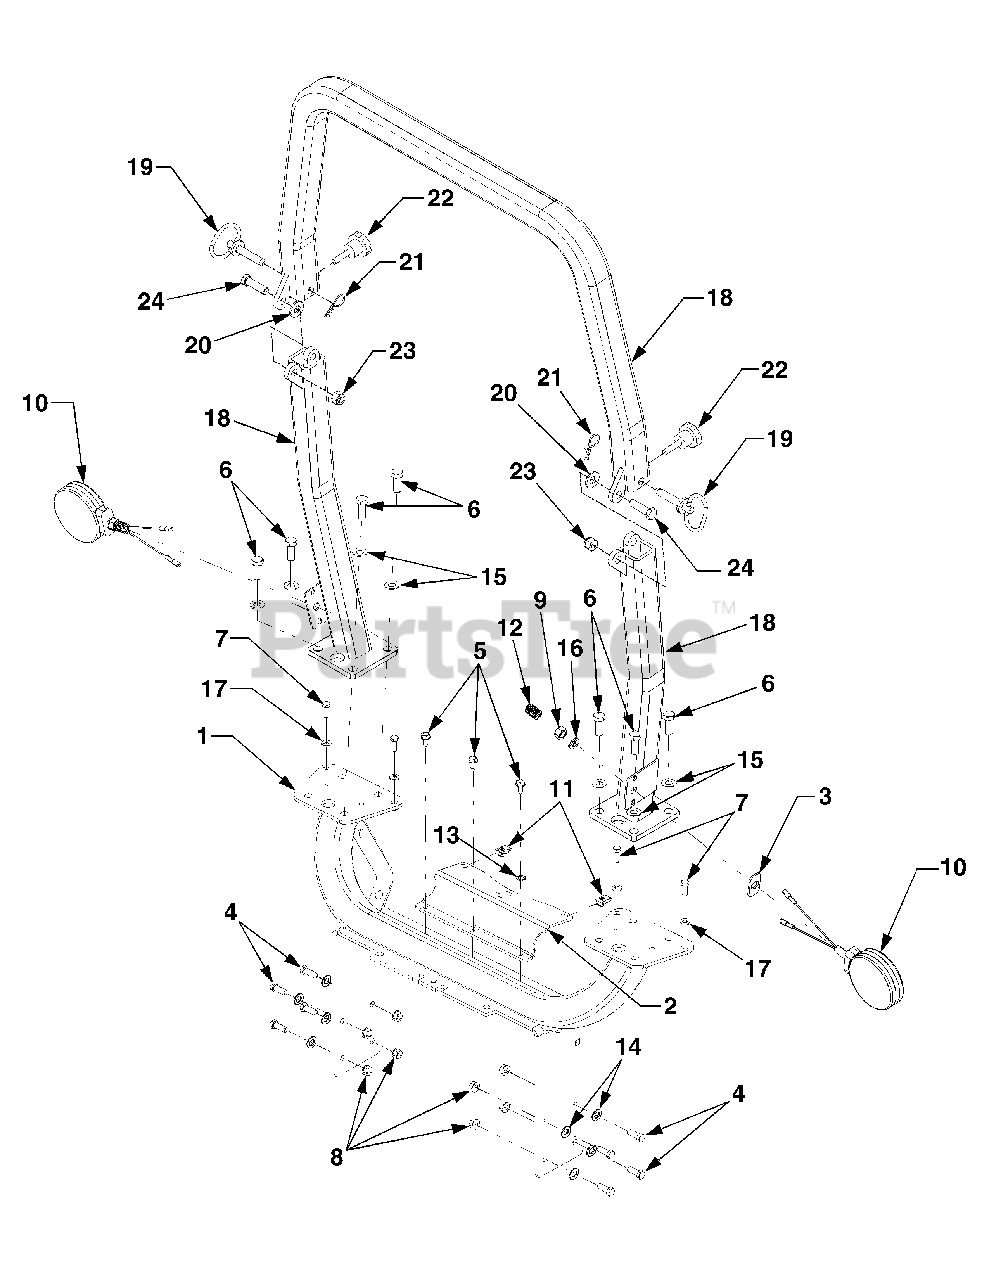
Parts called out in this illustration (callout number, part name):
1	Rops, Lower
2	Bracket, Rear Seat Mounting
3	Plate, Spacer
4	Screw, HHC, 3/8-16 x 1.0 GR5
5	Screw, Hex Wash. Hd. Tapp 5/16-18-.75
6	Scrw, Hx Lk, 1/2-13 x 1.25 GR5
7	Scrw, HHC, 5/16-18 x .87 GR5
8	Nut, Hx. Insert Flage Lock, 3/8-16 GRF
9	Nut, Hex, 1/2-20 GR5
10	Light, Hazard
11	Nut, Speed, 5/16-18
12	Conduit
13	Washer, Ext. Tth Lock, 3/8 ...
14	Washer, Flat, .375 x .74 x .063
15	Washer, Flat, .51 x 1.0 x .060
16	Washer, Lock, 1/2
17	Washer, Flat, .345 x 1.0 x .10
18	Assembly, ROPS (Includes Ref . Nos. 19 thru 24)
20	Washer, Flat
21	Pin, Internal Cotter
22	Knob Assembly
23	Nut, Hex Insert Lock, 1/2-13
24	Scrw, HHC, 1/2-13 x 1.75 GR5
